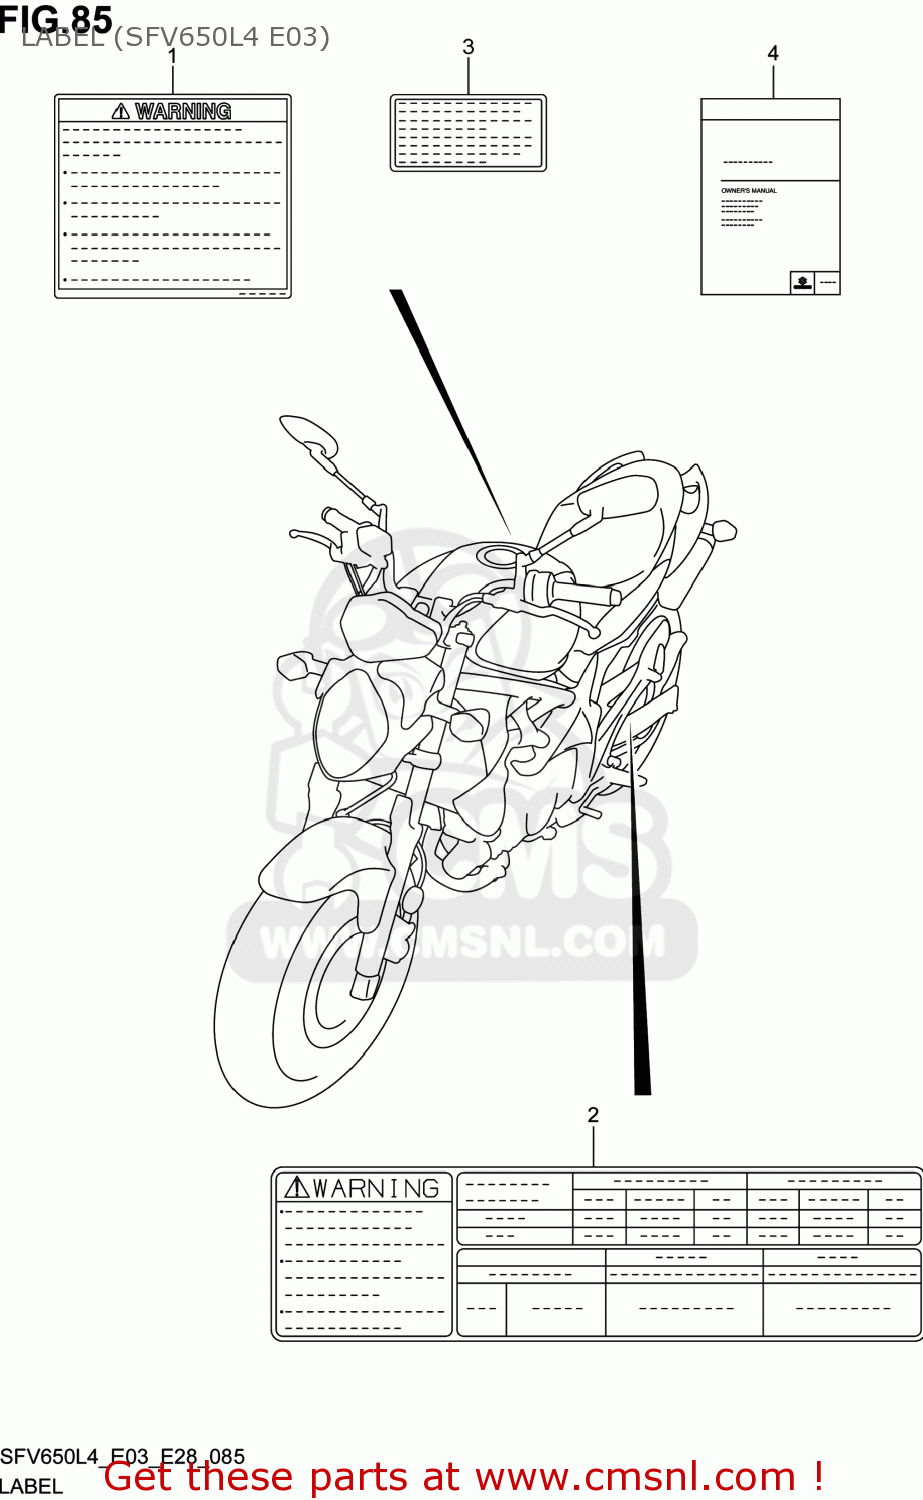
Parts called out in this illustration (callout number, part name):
1	LABEL,GENERAL WARNING
2	LABEL,TIRE INFORMATION
3	LABEL,MANUAL NOTICE
4	MANUAL,OWNER'S
